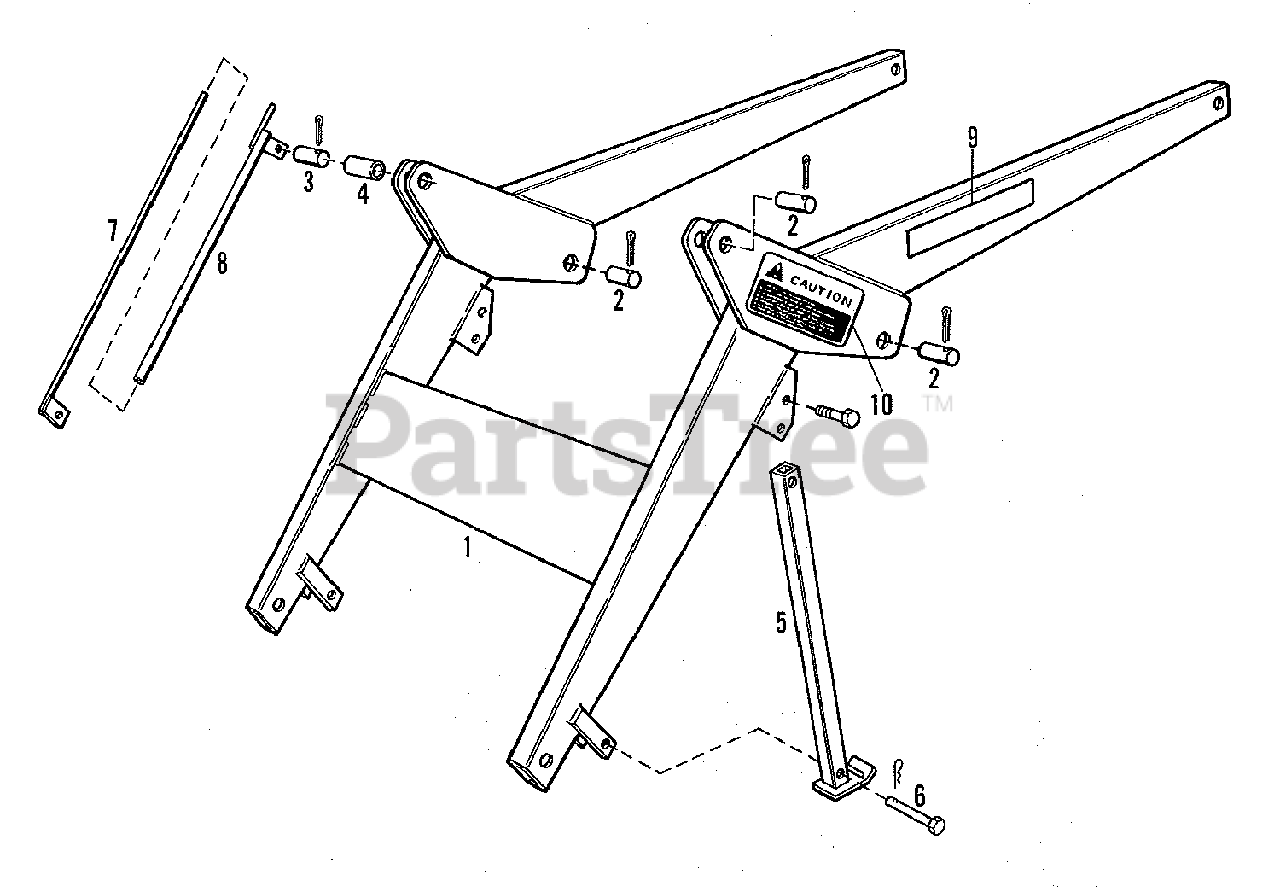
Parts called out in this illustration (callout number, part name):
1	BOOM ASSEMBLY
1	FITTING, Lube, 1/4 x 90 Degrees
2	PIN, Cylinder to Boom Assembly
2	PIN, Cotter, 1/4 x 2
3	PIN, Cylinder to Boom Assembly
3	CAPSCREW, 3/8NC x 3/4
3	WASHER, Plain, 3/8 x 7/8 x 14 Ga.
3	LOCKWASHER, 3/8
3	PIN, Cotter, 1/4 x 2
4	BUSHING, Pin
5	STAND ASSEMBLY, Parking
5	CAPSCREW, 3/8NC x 2-1/2
5	LOCKWASHER, 3/8
6	PIN, Parking Stand
6	CLIP, Hairpin, No. 3
7	ROD, Bucket Indicator
8	TUBE ASSEMBLY, Bucket Indicator
9	DECAL (415 Model Identification)
10	DECAL (Warning)
